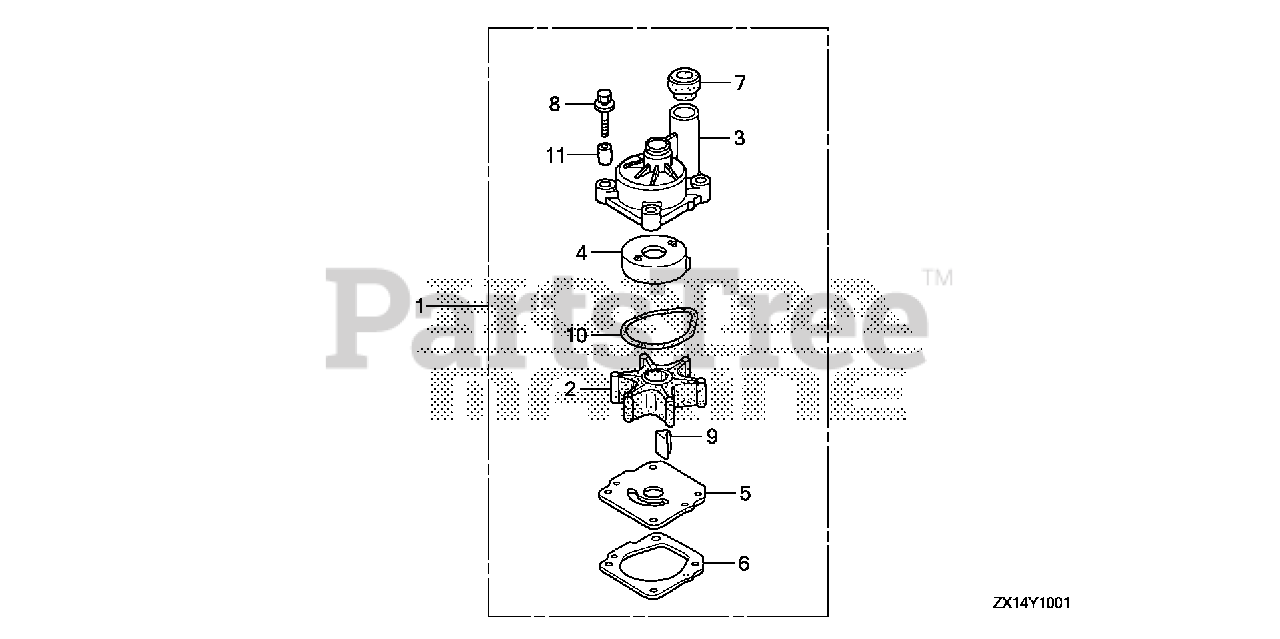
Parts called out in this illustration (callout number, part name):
1	PUMP KIT, IMPELLER
2	IMPELLER, PUMP
3	HOUSING, IMPELLER
4	LINER, PUMP
5	COVER, IMPELLER
6	GASKET B, IMPELLER
7	RING, WATER TUBE SEAL
8	BOLT-WASHER (8X40)
9	KEY, WOODRUFF
10	O-RING, WATER PUMP
11	COLLAR, DISTANCE
